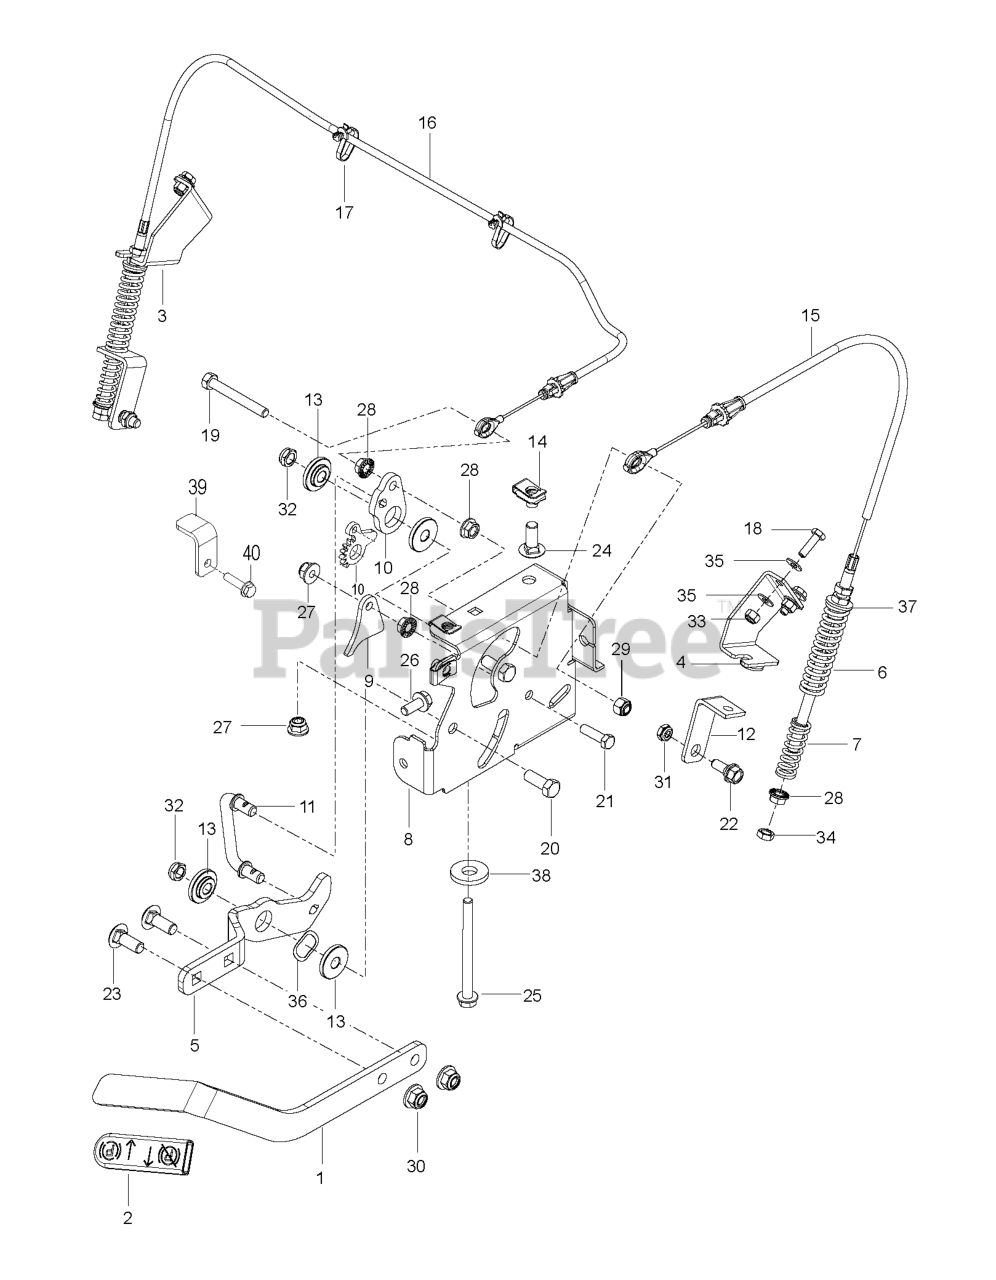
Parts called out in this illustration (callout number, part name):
1	ARM, BRAKE
1	ARM BRAKE BLACK MS-431
2	GRIP, PARK BRAKE
3	BRKT, BRAKE RT, BLK
3	BRACKET BRAKE, RT BLACK MS-431
4	BRKT, BRAKE LT, BLK
4	BRACKET BRAKE, LT BLACK MS-431
5	LEVER.PNT.BRAKE.E-DIP
5	GEAR.INPUT.PARKING.BRAKE.MZ
6	SPRING, RETURN
7	SPRING, ENGAGEMENT
8	MOUNT.BRAKET.PNT.BLACK.MS431
8	MOUNT.PNT.BRAKE.MZ.EDIP
9	ACTUATOR, SWITCH
10	GEAR OUTPUT;PARKING BRAKE;STAN
10	BELLCRANK, BRAKE
11	LINKAGE, BRAKE
12	BRKT, BRAKE, BLK
13	BUSHING, BRAKE
14	U-CLIP 5/16-18 NUT RETAINER
15	CABLE.ASSY.BRAKE.CABLE.SHORT
16	CABLE.ASSY.BRAKE.CABLE.LONG
17	TIE WRAP, 8-3/8", W/CLIP
18	HCS 1/4-20X7/8 GR5
19	HCS 5/16-18 X 2 1/2 TPBLT
20	HCS 3/8-16X1.GRD.5.ZD
21	HCS 5/16C X 1
22	BOLT, SHOULDER
23	RHSNB 3/8C X 1
24	BOLT 5/16C X 3/4" CARRIAGE
25	HHFS 5/16-18 X 3 3/4
26	HHFS 5/16-18 X 3/4
27	5/16-18 NYLOC FLANGE NUT
28	NUT 5/16C HEX
28	NUT 5/16C WHIZ
29	NUT 5/16 NYLOC
30	NUT 3/8-16 HEX FLG NYLOC ZD
31	5/16-18 THIN PROF NY
32	NUT HEX 3/8-16 NYLON, THIN
33	NUT.1/4-20.HEX.NYLOC.ZD
34	NUT 5/16-18 HEX JAM ZD
35	WASHER 1/4 SAE
36	WASHER, .825 X 1.087, WAVE
37	WASHER 3/8 SAE FLAT
38	WASHER.9/16 X 1 3/8 X 12 GA.
39	BRACKET.PNT.LIMIT.ARM.BRK.EDIP
40	HHFS 5/16-18 X 1.25 TPBLT GD 5
